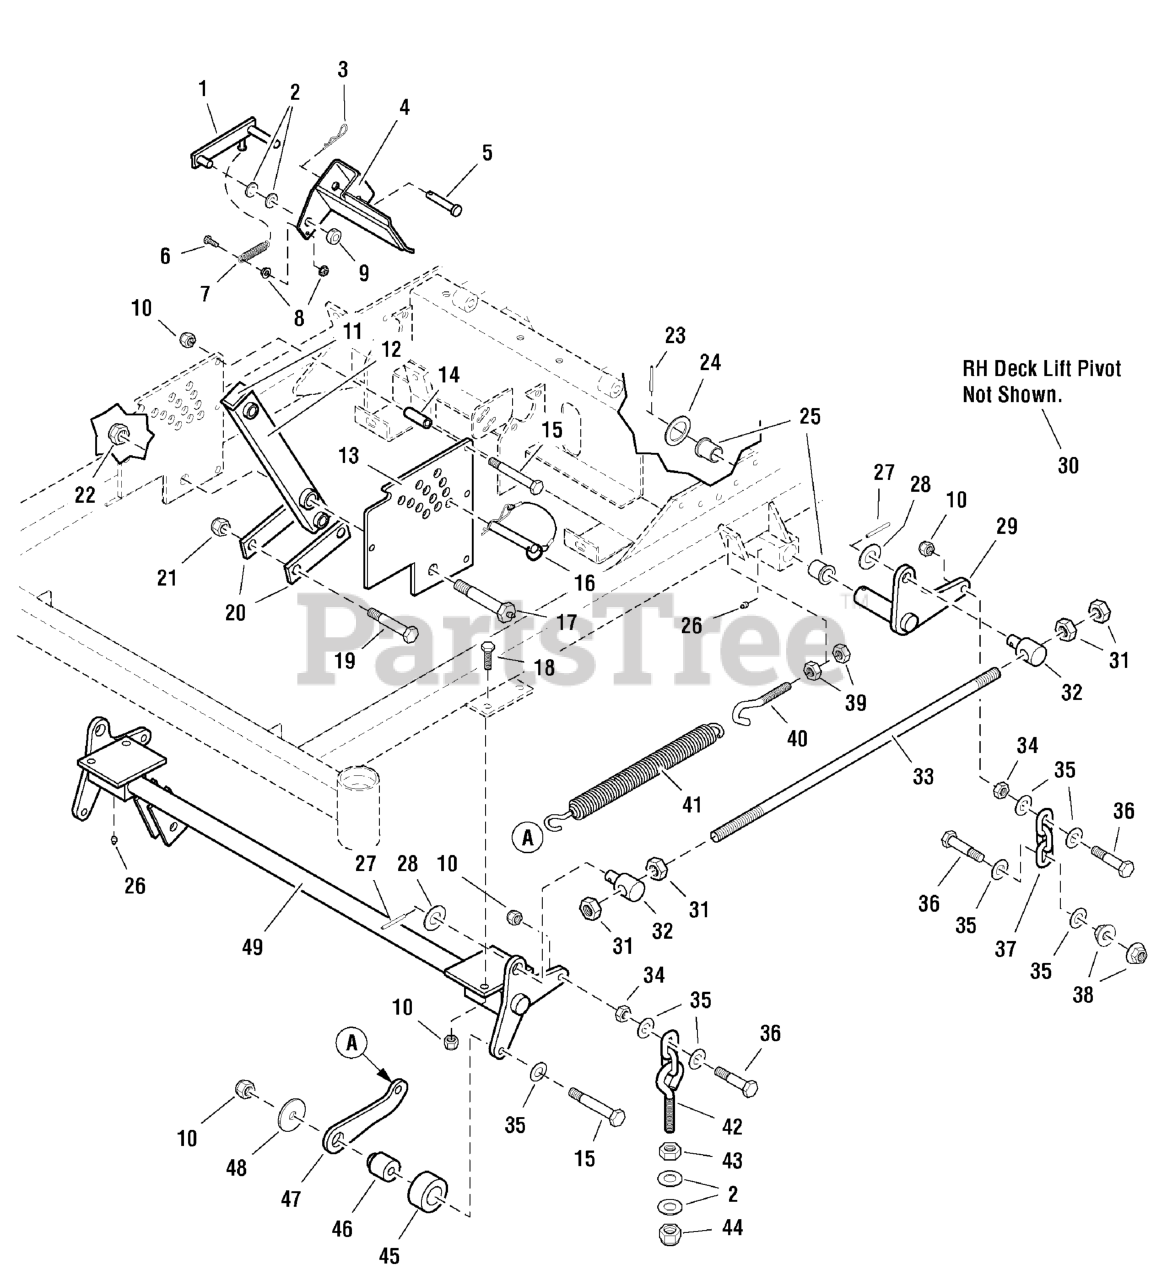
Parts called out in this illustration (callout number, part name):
1	DECK LIFT LOCK
2	WASHER, 1/2 SAE
3	HAIRPIN CLIP
4	WELD, DECK LIFT PEDAL
5	PIN, Clevis, 1/2 x 2-1/2
6	BOLT, 1/4-20 x 3/4
7	SPRING, Extension
8	NUT, 1/4-20 HEX SERR. FLANGE
9	COLLAR, Split, 1/2
10	NUT, 3/8-16 HEX NYLON LOCK
12	ARM, Deck Lift Pivot
13	DECK HEIGHT PLATE
14	SPACER, .38 x .50 x 1.56
15	BOLT, 3/8-16 X 2-3/4" GD5 CZ
16	PIN, 1/2 x 3-1/2 w/ Lanyard
17	LIFT PIVOT BOLT
18	BOLT, 3/8-16 X 1-1/4" GD5 CZ
19	BOLT, 1/2-20 x 3
20	LINK, Deck Lift
21	NUT, Hex, Nylon Lock, 1/2-20
22	NUT, 5/8-11 Hex Jam Nylon Lock
23	PIN, Roll, 3/16 x 1-1/2
25	BUSHING, Flange
26	GREASE FITTING
27	PIN, Spring, 3/16 x 1-1/4
28	WASHER, 5/8" SAE
29	DECK LIFT PIVOT-LH
31	NUT, 5/8-11 Hex
32	SPRING ROD PIVOT
33	DECK ADJUSTMENT ROD
34	NUT, 3/8-16 HEX JAM
35	WASHER, 3/8 SAE
36	BOLT, 3/8-16 X 1-3/4" GD5 CZ
37	CHAIN, 3 LINKS
38	NUT, 3/8-16 Hex Serrated Flange
39	NUT, 3/8-16 Hex
40	SCREW HOOK, 3/8-16 x 4-1/4
41	DECK LIFT SPRING
42	HANGER, FRONT DECK-2LINK, 5.5" EB
43	NUT, 1/2-13 Hex
44	NUT, 1/2-13 HEX NYLON LOCK
45	DECK STOP
46	DECK PIVOT BUSHING
47	SPRING LINK
48	WASHER, 3/8 x 2
49	DECK LIFT SHAFT & MOUNT ASSEMBLY
